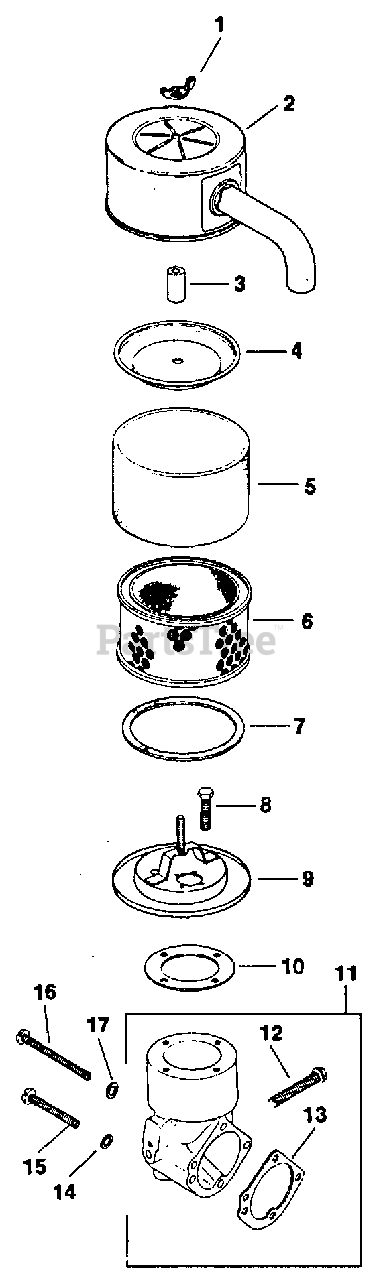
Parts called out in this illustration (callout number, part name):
1	WING NUT
2	COVER, AIR CLEANER
3	SEAL ELEMENT
4	COVER, AIR CLEANER ELEMENT
5	PRE-CLEANER
6	ELEMENT, AIR CLEANER
7	SEAL
8	SCREW
9	BASE, AIR CLEANER
10	GASKET
11	KIT, ELBOW
12	SCREW
13	GASKET, ELBOW
14	WASHER
15	SCREW
16	SCREW
17	WASHER
